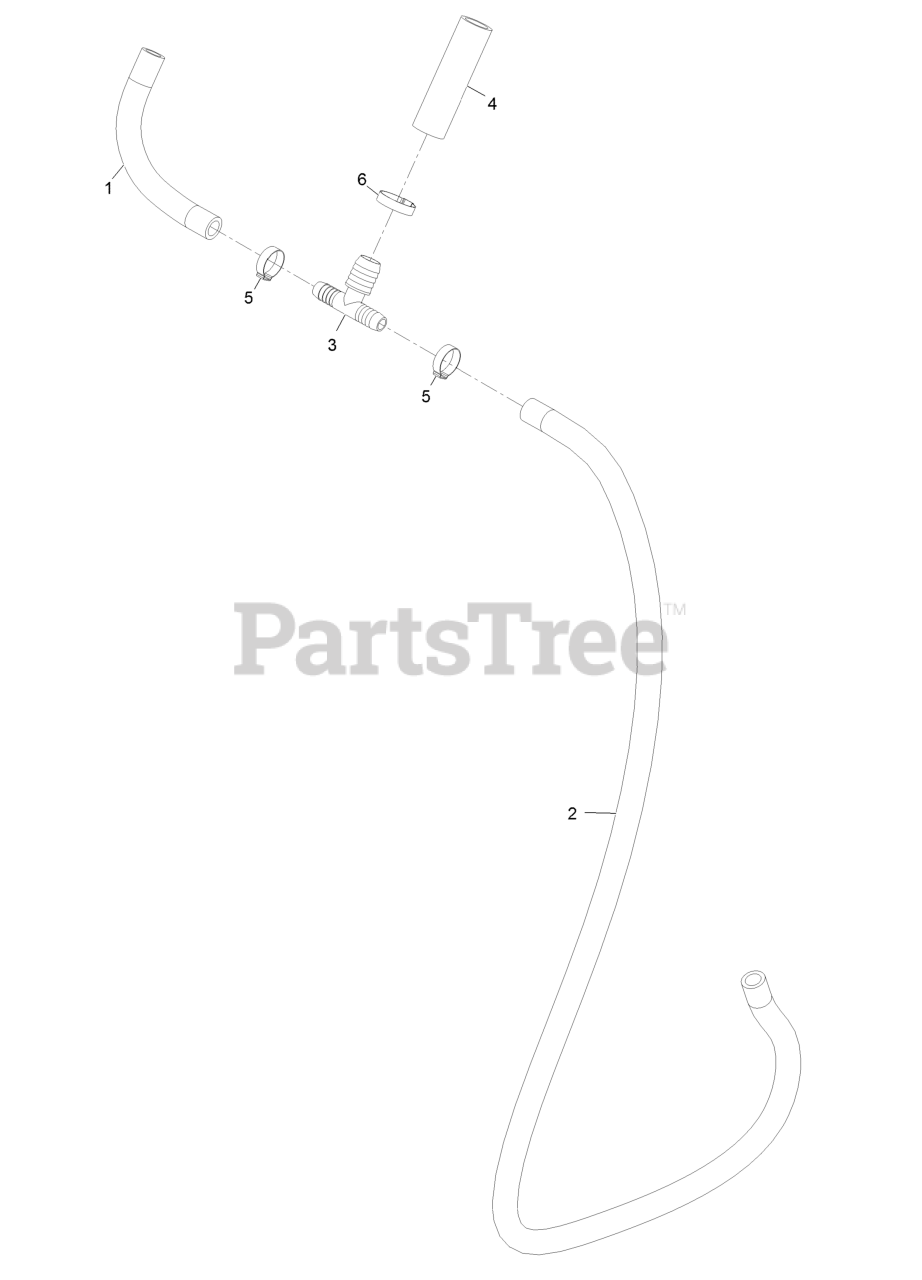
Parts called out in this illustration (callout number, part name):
1	Hose-Water
2	Hose-Water
3	Fitting-Tee
4	Hose-Water
